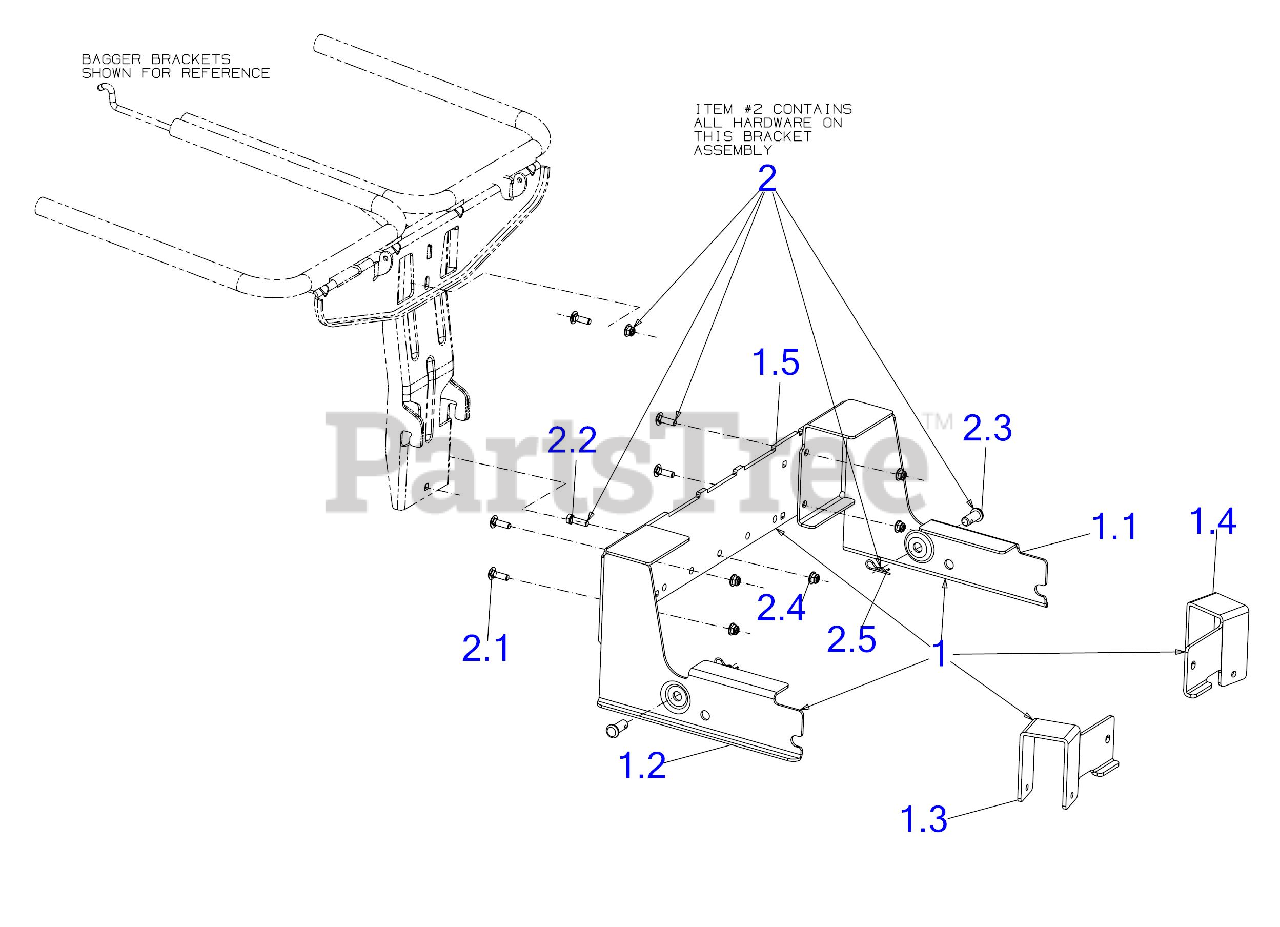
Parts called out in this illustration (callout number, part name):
1	BAGGER BRACKET ASSEMBLY
1.1	MOUNTING BRACKET (LH)
1.2	MOUNTING BRACKET (RH)
1.3	WEIGHT MOUNTING BRACKET (RH)
1.4	WEIGHT MOUNTING BRACKET (LH)
1.5	SUPPORT PLATE
2	HARDWARE PACK
2.1	CARRIAGE BOLT 5/16-18 x 1.00
2.2	SCREW 5/16-18 x 1.0 GR5
2.3	CLEVIS PIN .50 x 1.18
2.4	FLANGE LOCK NUT 5/16-18
2.5	COTTER PIN
